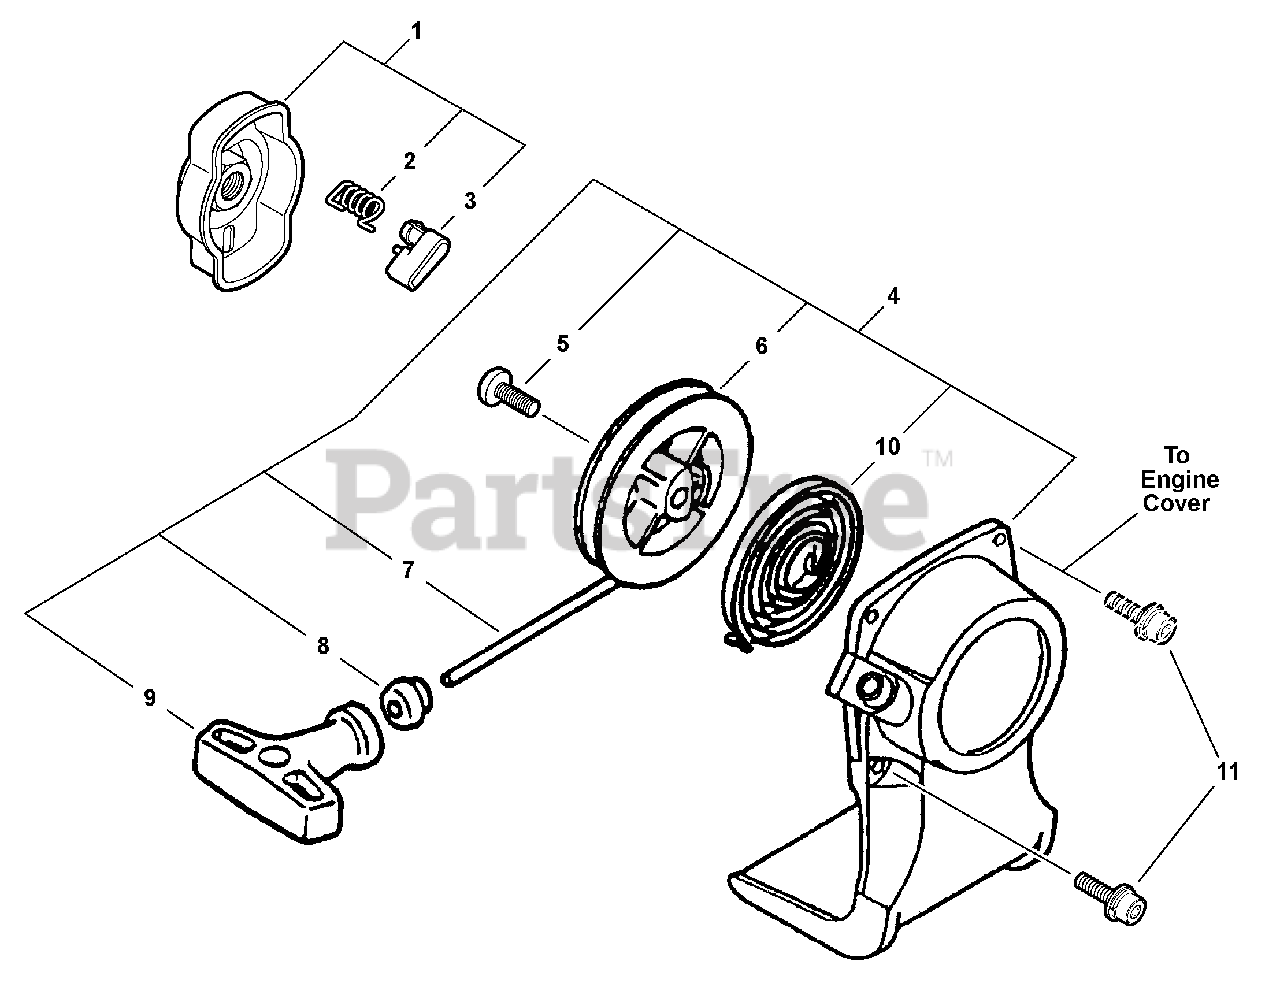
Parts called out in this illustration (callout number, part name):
1	PAWL ASSY, STARTER
2	SPRING, RETURN
3	PAWL, STARTER - BLACK
4	STARTER ASSY
5	SCREW
6	REEL, ROPE
7	ROPE, STARTER 3.0×1000
8	GUIDE, ROPE
9	GRIP, STARTER
10	SPRING, RECOIL
11	BOLT 4×16
